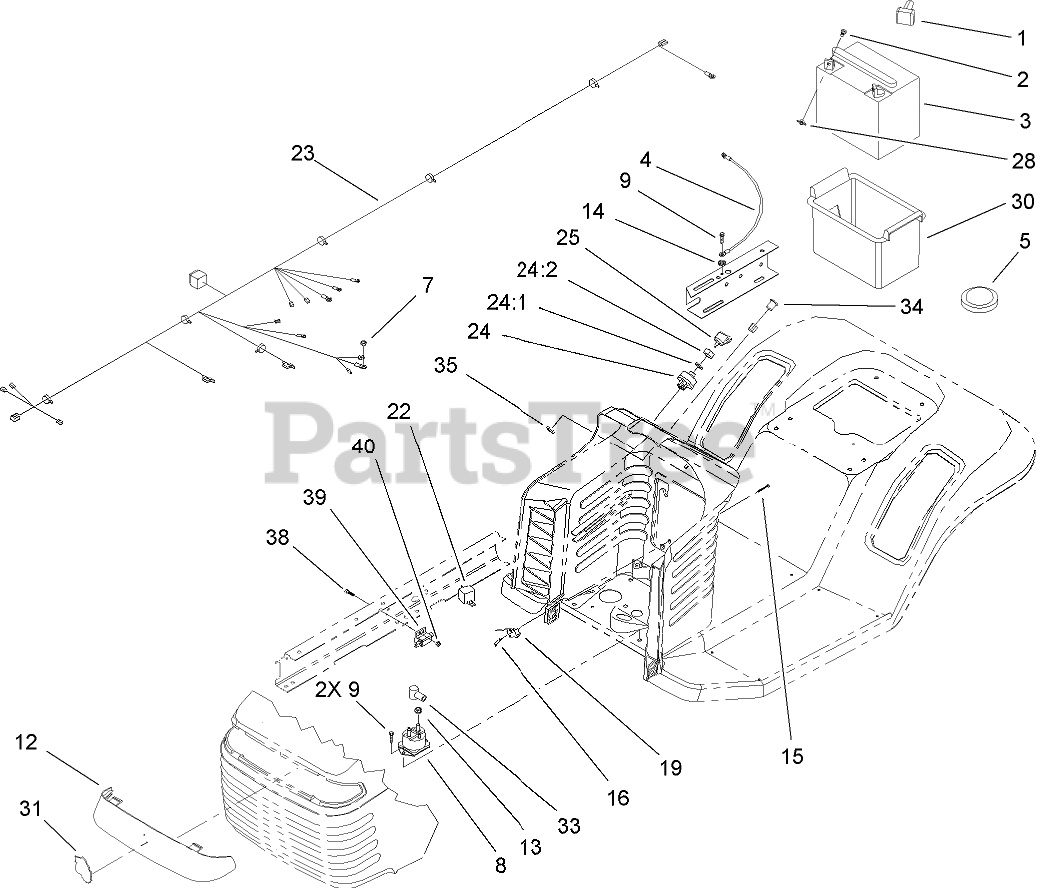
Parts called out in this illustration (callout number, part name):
1	BOOT-TERMINAL
2	SCREW-HH
3	BATTERY-155 CCA
4	WIRE ASM
5	SWITCH-SEAT
7	NUT-KEPS
8	SOLENOID-STARTER
9	SCREW-HWH
12	LENS-HEADLIGHT
13	NUT-KEPS
14	WASHER-LOCK/EXT
15	SCREW-HH
16	NUT-SPEED
19	SWITCH-MICRO
22	RELAY
23	HARNESS-WIRE
24	Key Switch ASM
24:1	WASHER-TOOTH, INTERNAL
24:2	NUT-HH
25	KEY-IGNITION
28	NUT-WING
30	BOX-BATTERY
31	EMBLEM
33	BOOT-INSULATOR, TERMINAL
34	LIGHT-INDICATOR
35	NUT-PUSH-ON, CIRCULAR
38	SCREW-HSH
39	SWITCH-POLE, SINGLE
40	NUT-LOCK, NI
